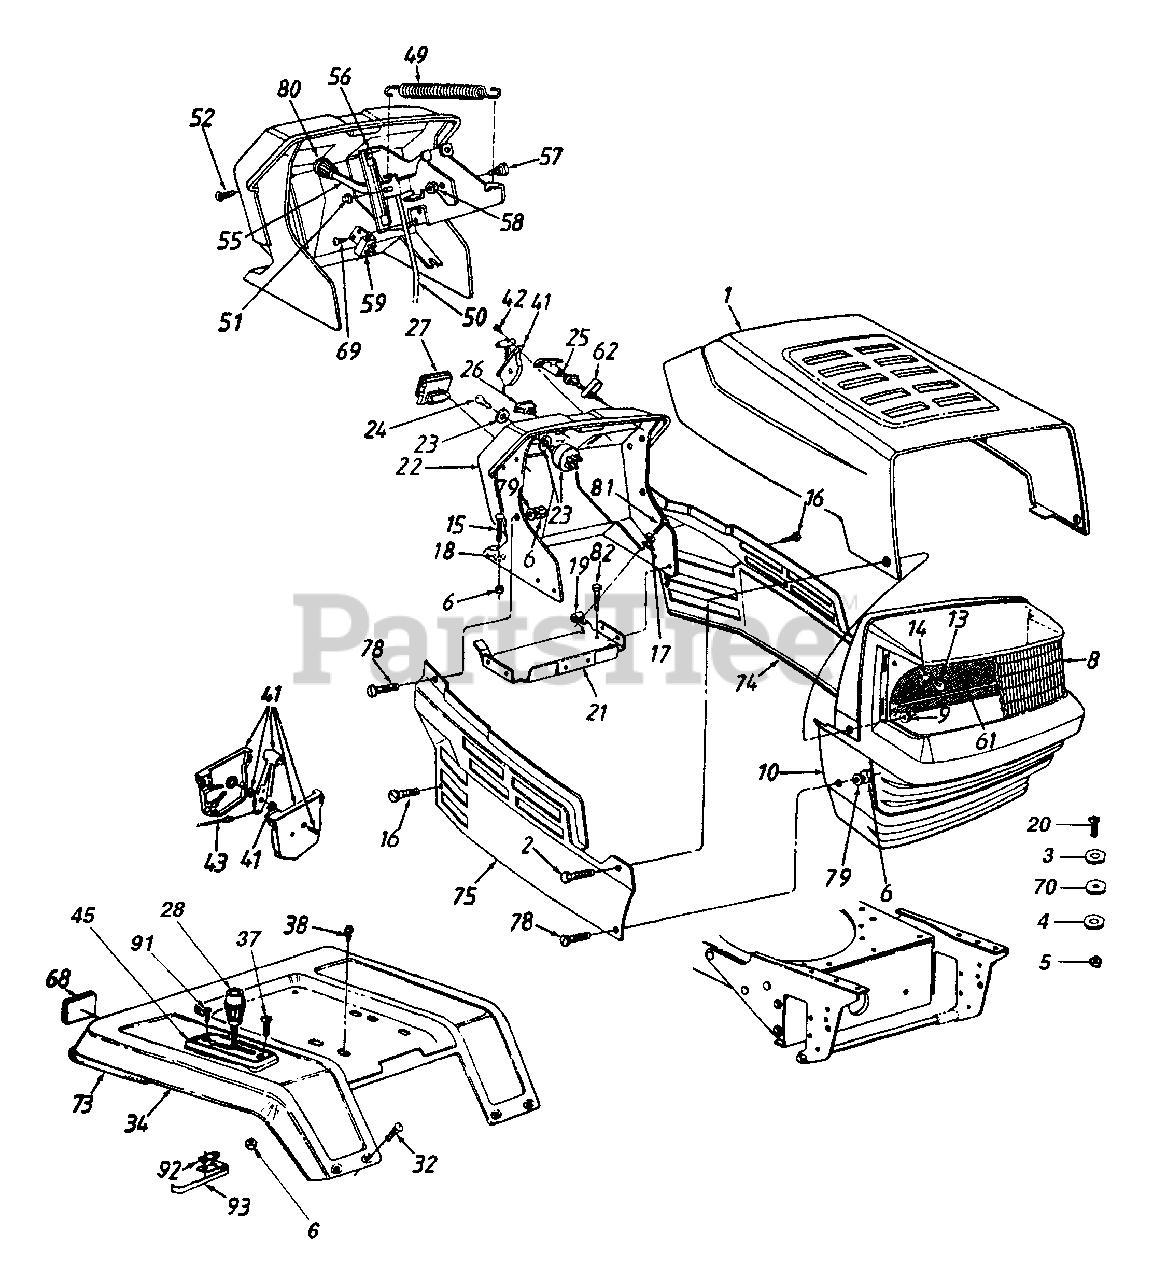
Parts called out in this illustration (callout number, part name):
3	Fl-Wash. .34" I.D. x 1" O.D.
4	L-Wash. 5/16" I.D.
5	Hex Nut 5/16-18 Thd. (Gr. 5)
6	Hex Sems Nut 1/4-20 Thd.
8	Headlight Lens w/Logo
9	Flange L-Nut 1/4-20 Thd.
10	Grille
13	Lamp
14	Socket
15	Carriage Bolt 1/4-20 x 1.0" Lg.
16	Hx Wash Hd. TT-Tap Scr. 1/4-20 x .5"
17	Fl-Wash. .281" I.D. x .73" O.D.
18	Bolt Retainer 1/4" I.D.
19	Speed Nut 1/4-20 Thd.
20	Hex Bolt 5/16-18 x .75" Lg.
23	Ignition Switch
24	Ignition Key
25	Choke Control
27	Ammeter
28	Shift Knob
32	Carriage Bolt 1/4-20 x .5" Lg.
38	Hx Wash Hd. AB-Tap Scr. 5/16 x .75"
41	Throttle Box Ass'y.
42	Truss Mach. AB-Tap Scr. #10 x .5" Lg.
43	Throttle Control Wire 35" Lg.
45	Selector Plate
49	Ext. Spring 5.06" Lg.
50	Deck Control Rod
51	Speed Nut 1/4" Rod
52	Torx Mach. Scr. 1/4 x .62" Lg.
55	PTO Lever
58	Hex L-Nut 5/16-18 Thd.
59	Safety Switch
61	Grille Reflector Label
62	Retainer Clip
68	Reflector
69	Hx Wash. Hd. B-Tap Scr. #10 x .38" Lg.
70	U-Nut 5/16-18 Thd.
73	Trim Strip 81" Lg.
79	Bell-Wash. 1/4" I.D.
81	Hex TT-Tap Scr. 1/4-20 x .75" Lg.
82	Hex AB-Tap Scr. 1/4 x .62" Lg.
91	Hex Wash. Hd. AB-Tap Scr.
92	Insulator Nut Plate
93	Reverse Safety Switch
